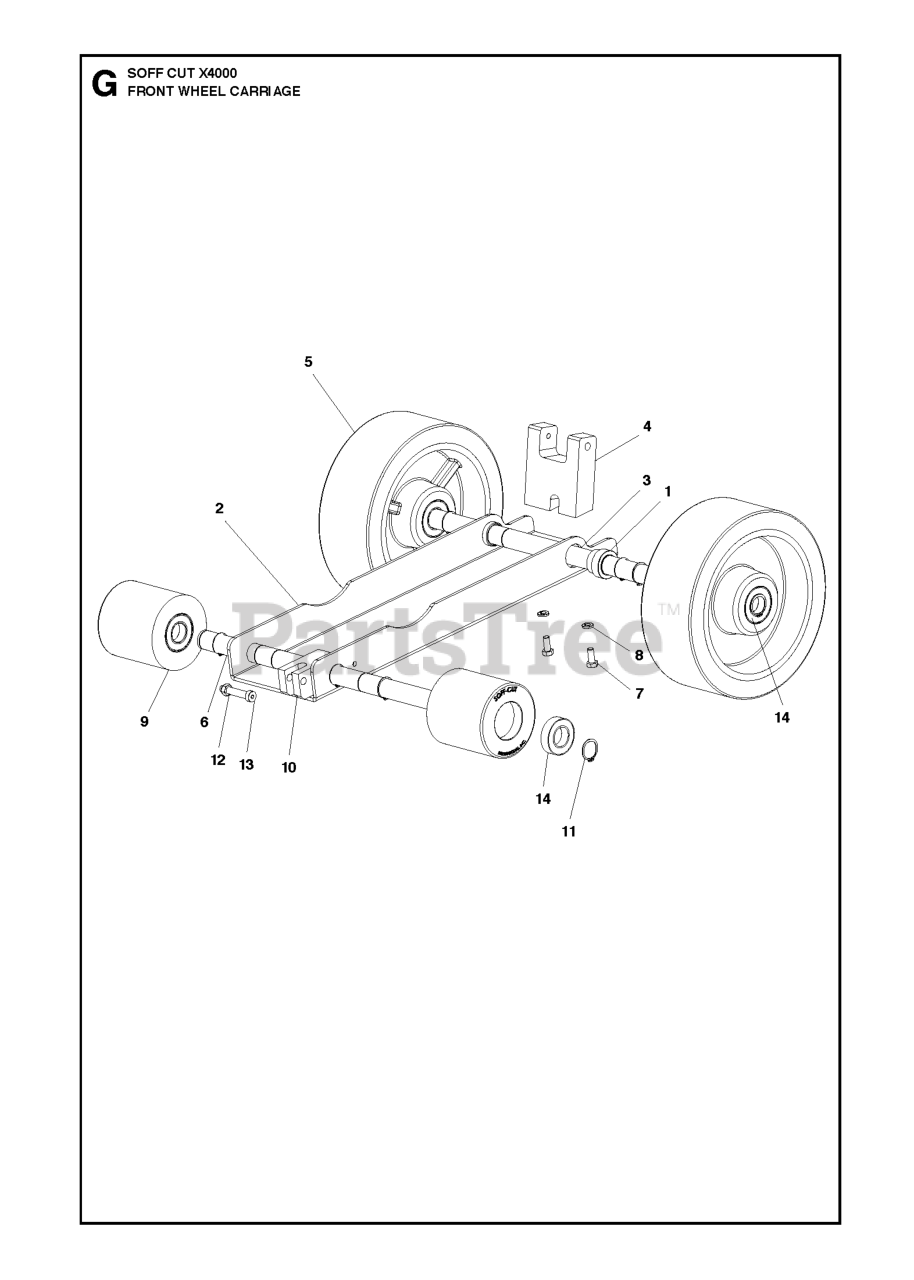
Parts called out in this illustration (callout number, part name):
7	SCREW
12	NUT
14	WHEEL2 pcs incl. In each wheel.
